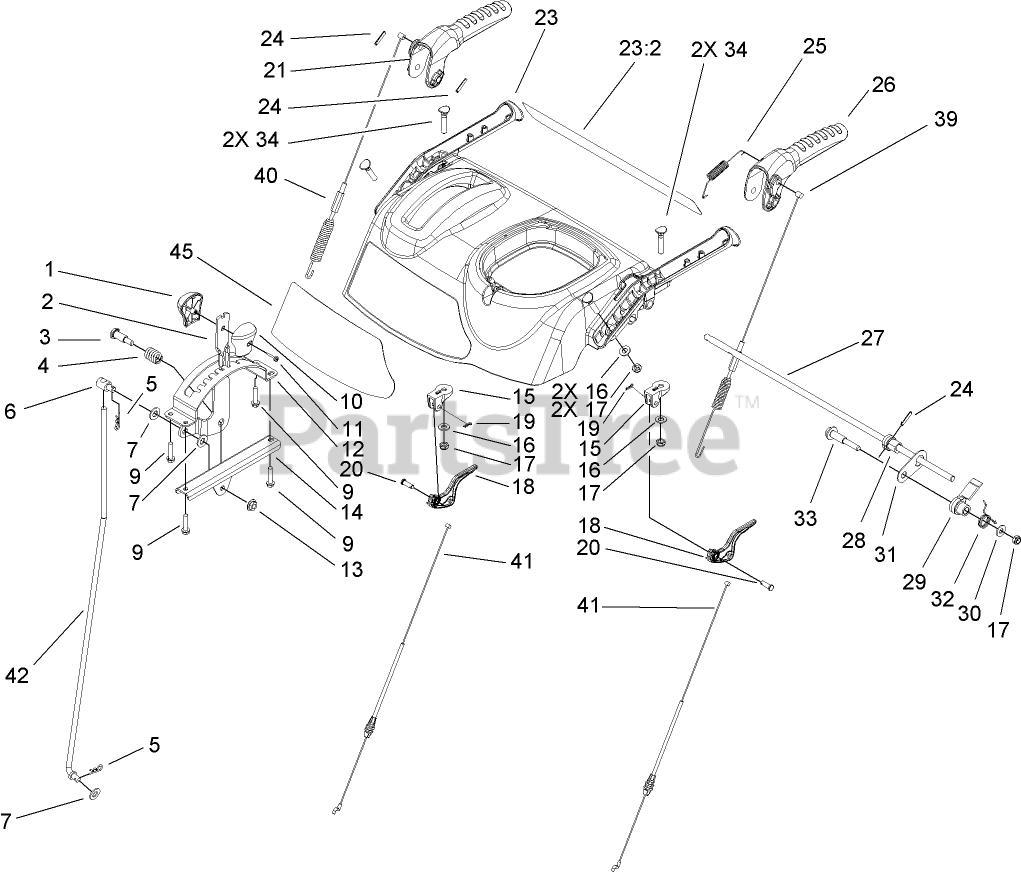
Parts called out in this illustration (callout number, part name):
1	KNOB-SHIFT, RH
2	SELECTOR-SPEED
3	SCREW-SHOULDER
6	TRUNNION-ROD
7	WASHER-FLAT
9	SCREW-PLASTITE
10	KNOB-SHIFT, LH
11	SCREW-PPH
12	GUIDE-SELECTOR, SPEED
13	NUT-HF
14	MOUNT-SELECTOR, SPEED
15	MOUNT-LEVER, CLUTCH
16	WASHER-FLAT
17	NUT-LOCK, NI
18	LEVER-CLUTCH
19	PIN-HAIR
20	PIN-CLEVIS
21	LEVER-AUGER
23	PANEL-CONTROL
23:2	DECAL-WARNING
24	PIN-SPRING
25	SPRING-TENSION
26	LEVER-TRACTION
27	ROD-LOCKOUT
28	CAM-LOCKOUT
29	LATCH-LOCKOUT
30	WASHER-FLAT
31	LINK-LOCKOUT
32	SPRING-TORSION
34	SCREW-HANDLE
41	CABLE-CLUTCH
